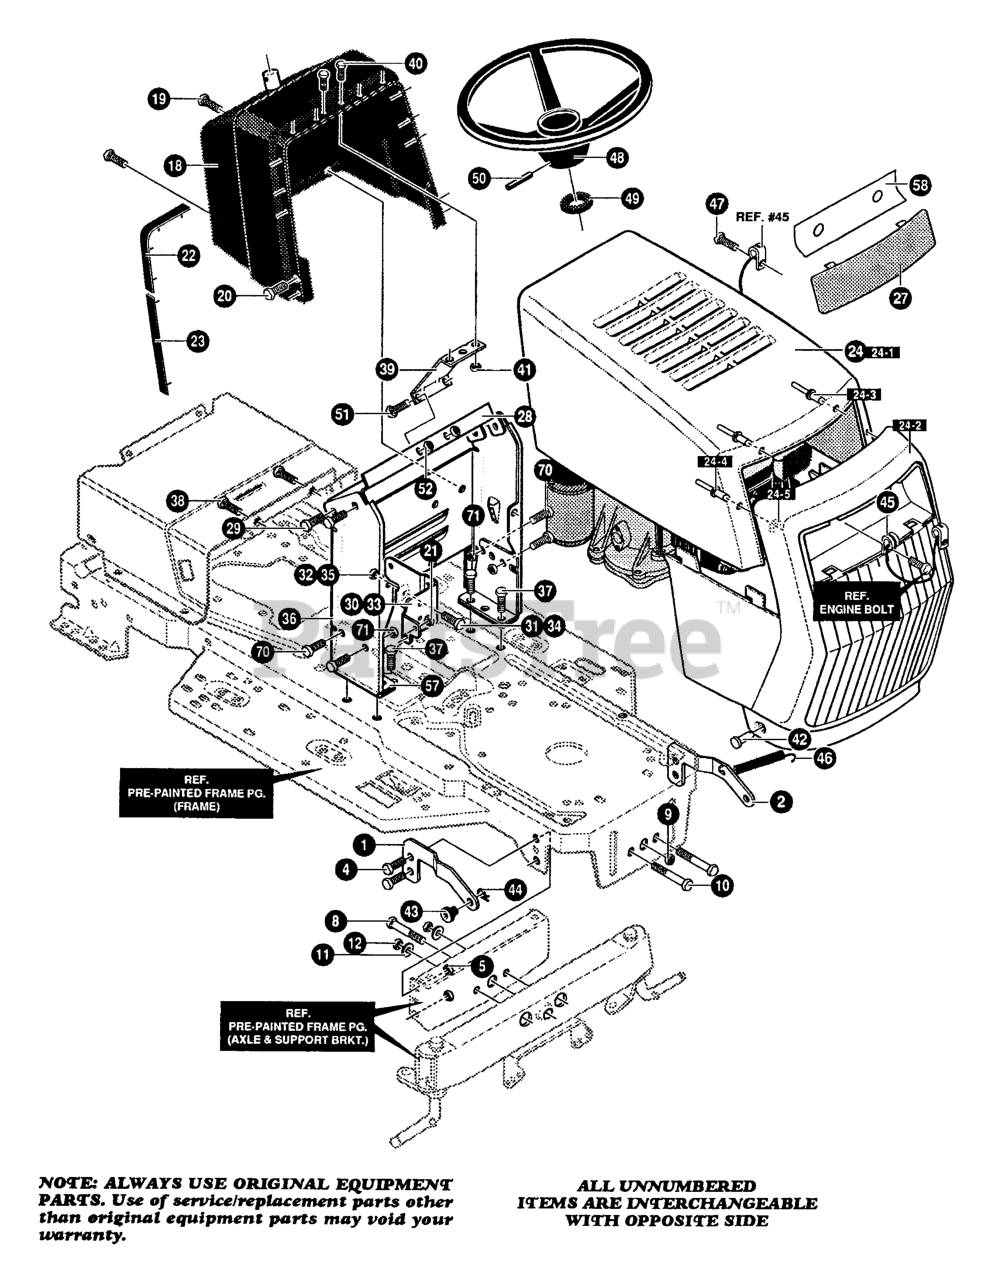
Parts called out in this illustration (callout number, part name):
1	BRACKET, HOOD RH
2	BRACKET, HOOD LH
4	SCREW, 5/16-18 x 0.75
5	NUT, 5/16-18
8	BOLT, .625 X 2.18
9	NUT, 1/2-13
10	SCREW, 3/8-16 x 3.00
11	WASHER, .39ID X 1.25D X .07
12	NUT, 3/8-16
19	SCREW, 1/4-14 X .75
20	SCREW, 10-24 X .63
21	NUT, #10-24
22	BUMPER, HOOD/DASH TOP & CORNER
23	BUMPER, HOOD/DASH SIDE STRIP
24	HOOD ASSEMBLY
24-1	HOOD KIT
24-2	HOOD KIT
24-3	RIVET, POP
24-4	RIVET, POP
24-5	FLATWASHER, .203 X .56 X .040
27	LENS, GRILLE
28	SUPPORT, STEERING/PTO
29	SCREW, 1/4-20 X .38
30	BRACKET, DASH/TANK, RH
31	SCREW, 1/4-20 X .75
32	NUT, 1/4-20
33	BRACKET, DASH/TANK, LH
34	SCREW, 1/4-20 X .75
35	NUT, 1/4-20
36	DASH, TOWER WALK-THRU
37	SCREW, 5/16-18 x 0.50
38	SCREW, 1/4-20 X .38
39	DASH, SUPPORT BRACKET
40	SCREW, 10-24 X .63
41	NUT, #10-24
42	PIN, CLEVIS
43	BEARING, HOOD
44	PIN, HAIR
45	LANYARD, HOOD 11.75 LONG
46	SPRING, HOOD LATCH
47	SCREW, 1/4-10x.75
48	STEERING WHEEL
49	SPACER, SLEEVE
50	PIN, SPRING
51	SCREW, 1/4-20 x .75
52	NUT, 1/4-20
57	BRACE, DASH TOWER
58	FOIL, LENS REFLECTOR
70	SCREW, 1/4-20 X .50
71	NUT, 1/4-20
